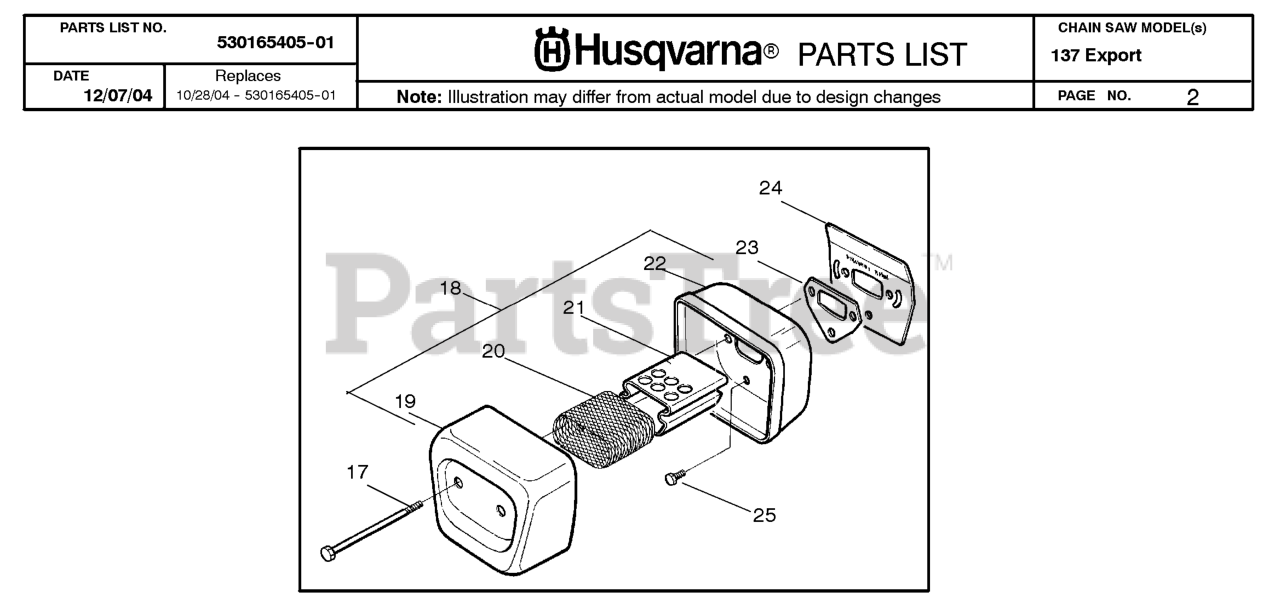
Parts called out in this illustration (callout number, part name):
18	MUFFLER KIT
19	SILENCER COVER
20	SPARK ARRESTOR 36/41
21	FLAME PROTECTOR
22	SILENCER BODY
24	MUFFLER PLATE
25	BOLT-MUFFLER(SUPPORT)
